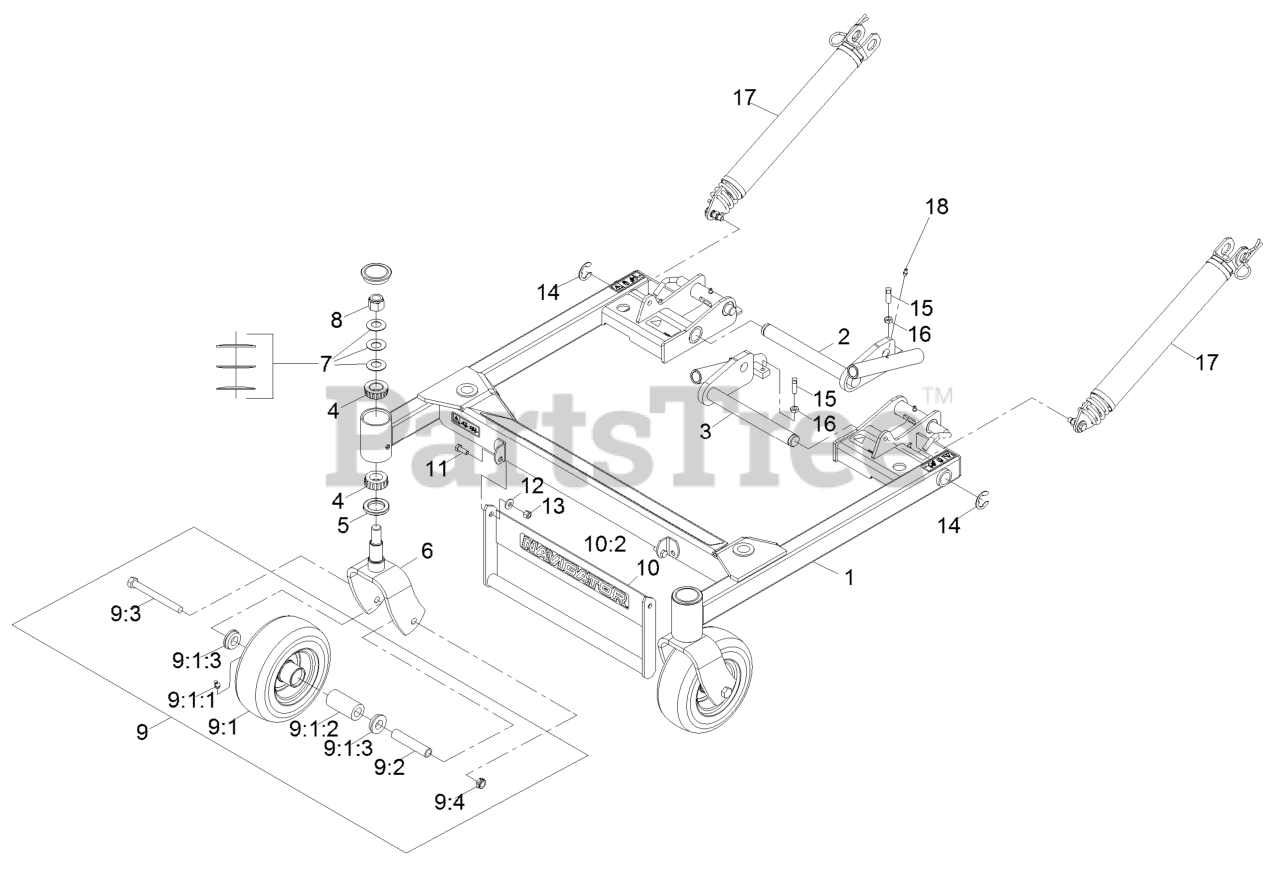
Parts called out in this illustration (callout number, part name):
1	DECK SUPPORT ASM
2	PIVOT-DECK, RH
3	PIVOT-DECK, LH
4	Cone-Bearing Tapered Roller
5	SEAL-GREASE
6	FORK-CASTER
7	WASHER-BELLVILLE
8	NUT-LOCK, NI
9	ASM,FF CASTER WHEEL W/AXL
9:1	ASM,WHEEL,TIRE & BRGS 8X3
9:1:1	FITTING-GREASE
9:1:2	BEARING-ROLLER, STRAIGHT
9:1:3	BUSHING
9:2	SPACER-CASTER, FRONT
9:3	SCREW-HH
9:4	NUT-HEX
10	ASM,DECK LIFT HANDLE W/DE
10:2	Decal-Navigator Logo
11	SCREW-HH
12	WASHER-SPRING
13	NUT-LOCK, NI
14	RING-SNAP
15	SCREW-SET, SQH
16	NUT-JAM
17	LIFT ASSIST SPRING ASM
18	FITTING-GREASE
